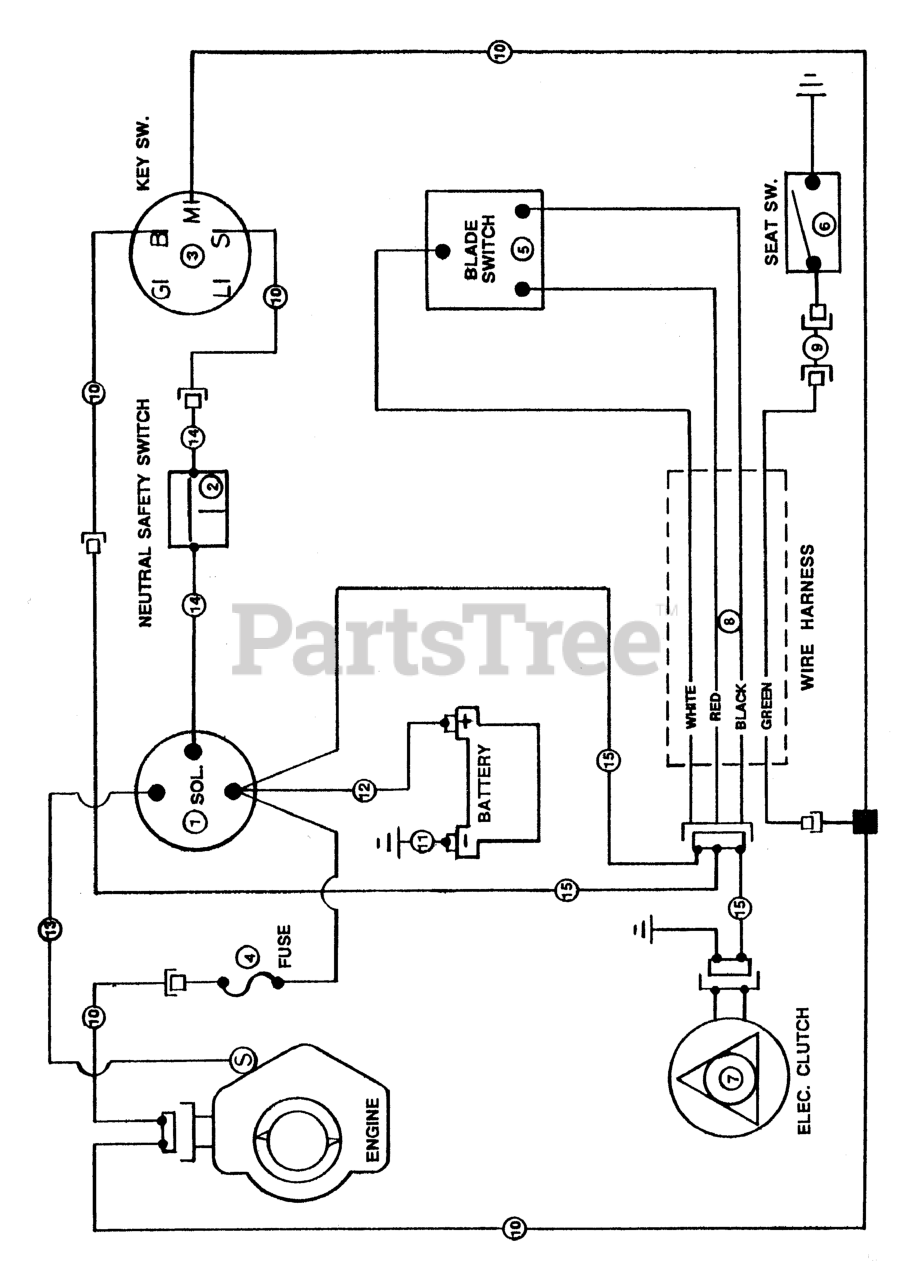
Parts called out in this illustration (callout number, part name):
1	SOLENOID, Starter
2	Neutral Safety Switch
3	SWITCH, Ignition
4	Fuse Holder Assembly
4	20 Amp Fuse
5	Toggle Switch
6	Seat Switch Assembly
7	CLUTCH, Electric, 1" Shaft
8	SJO Cable Electric Clutch Assembly
9	Green Alpha Cable to Seat Switch
10	Key Switch Wiring Harness
11	Negative Battery Cable
12	Positive Battery Cable
13	Solenoid to Starter
14	Neutral Safety Switch Wiring Harness
15	Electric Clutch Wiring Harness
